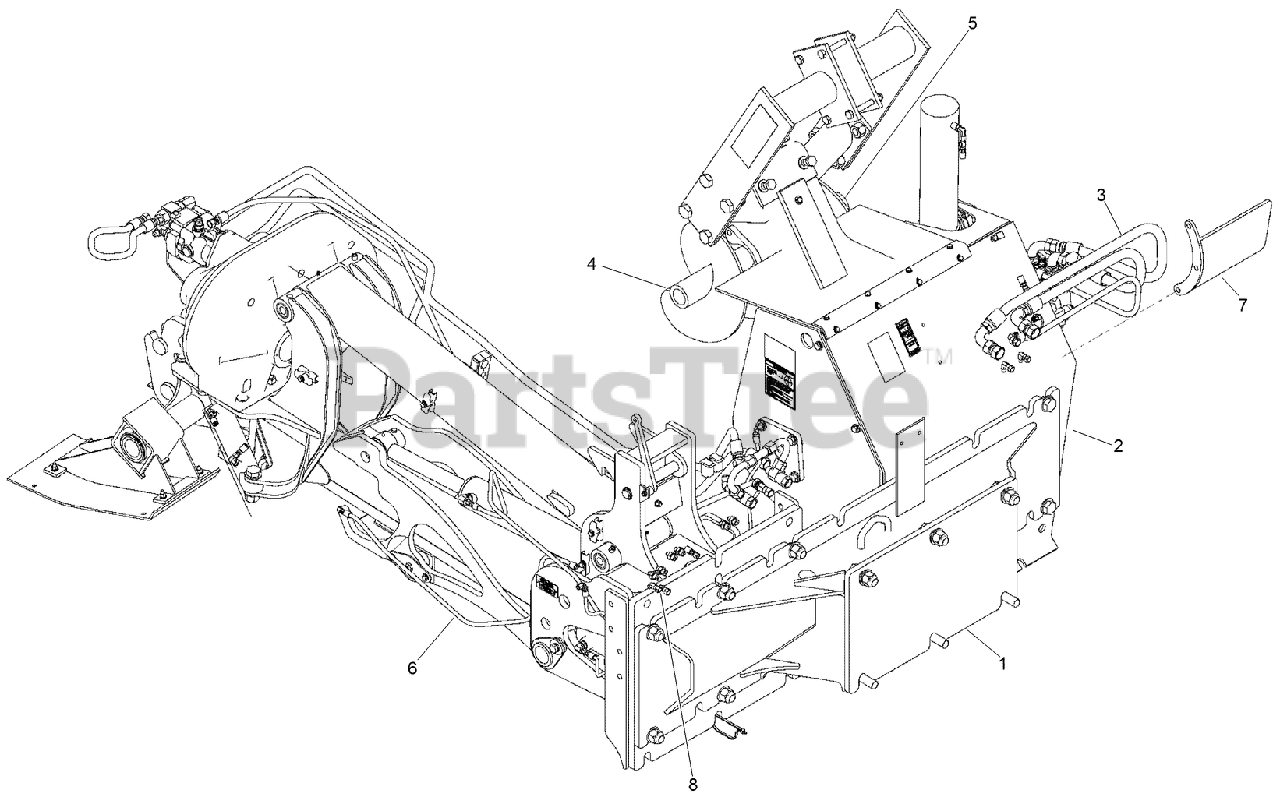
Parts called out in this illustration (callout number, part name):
1	WELDMENT - Quad Frame
2	KIT - Trencher
3	ATTACHMENT KIT - Trencher
4	WELDMENT - Auger, RH
5	WELDMENT - Auger, LH
6	ASSEMBLY - Plow
7	GUARD - Trencher Motor
8	Plow Swing Cylinder Stop ASM
